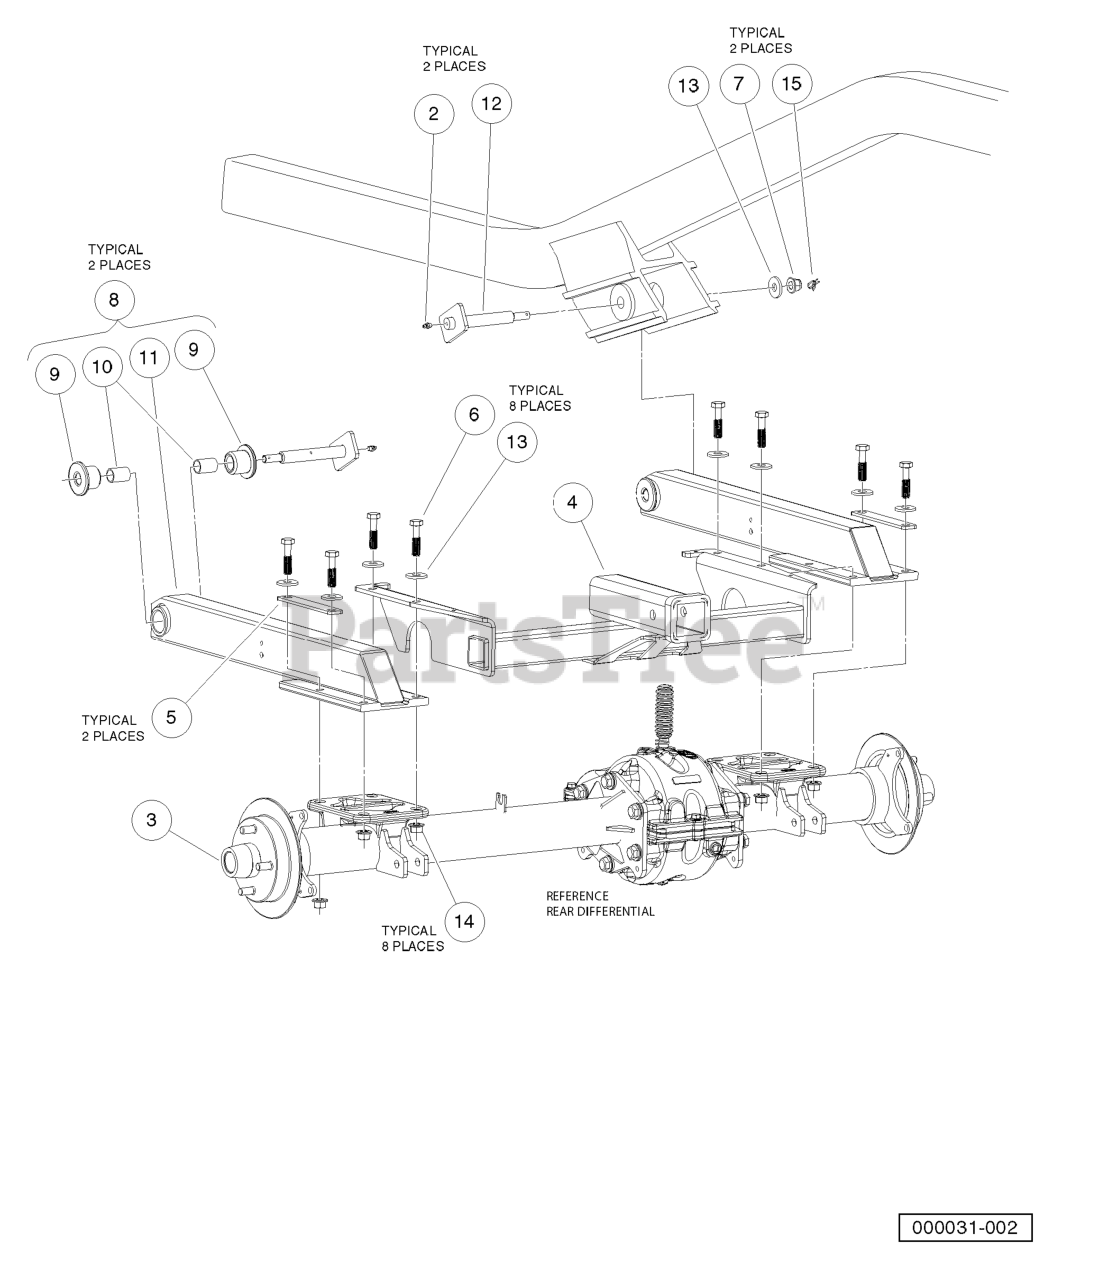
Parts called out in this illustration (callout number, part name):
1	Instl, Rear Suspension
2	FITTING, 1/4-28 THRD FRM GREAS
3	CENTER CAP, RUBBER
4	WELDMENT, RECEIVER, REAR
5	WASHER, STRIP, SWINGARM
6	BOLT FLG, M12X1.75X50
7	NUT FLG, M12X1.75, NYLON GR 10
8	Sub Asm Swingarm
9	BUSHING, PIVOT, URETHANE
10	BUSHING, TEFLON
11	SWINGARM, REAR, AWD
12	PIN, SWINGARM, WELDMENT
13	WASHER, M12 HARD REGULAR
15	COTTER-RUE RING
